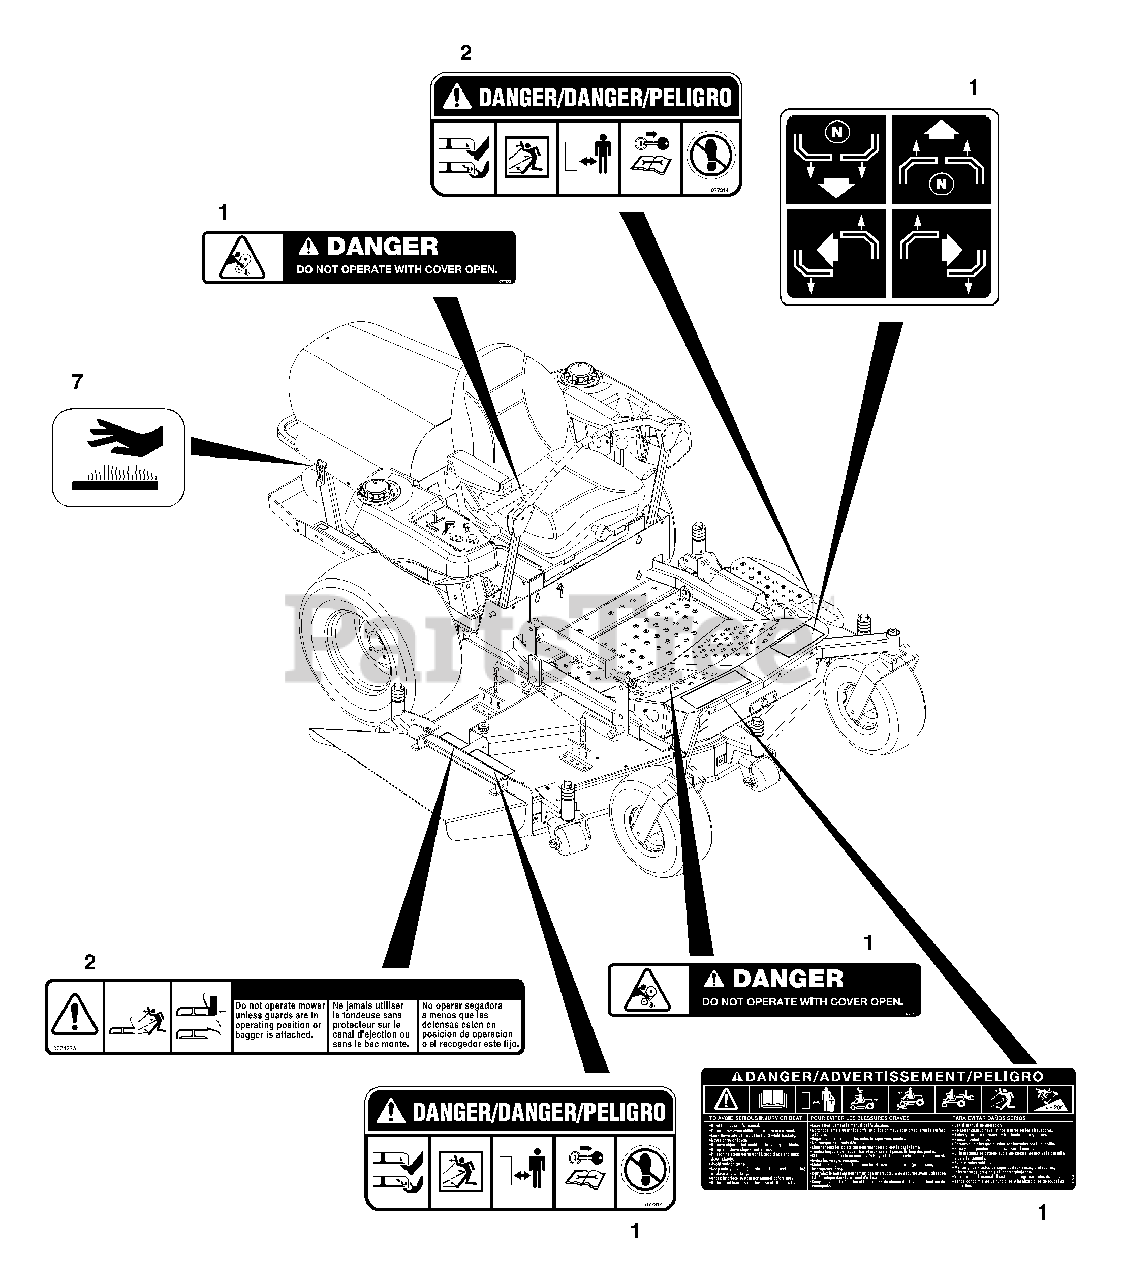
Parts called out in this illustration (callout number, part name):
1	Decal Set PM260Z
2	Decal Set Mower Decks
7	Decal-Hot Surface
